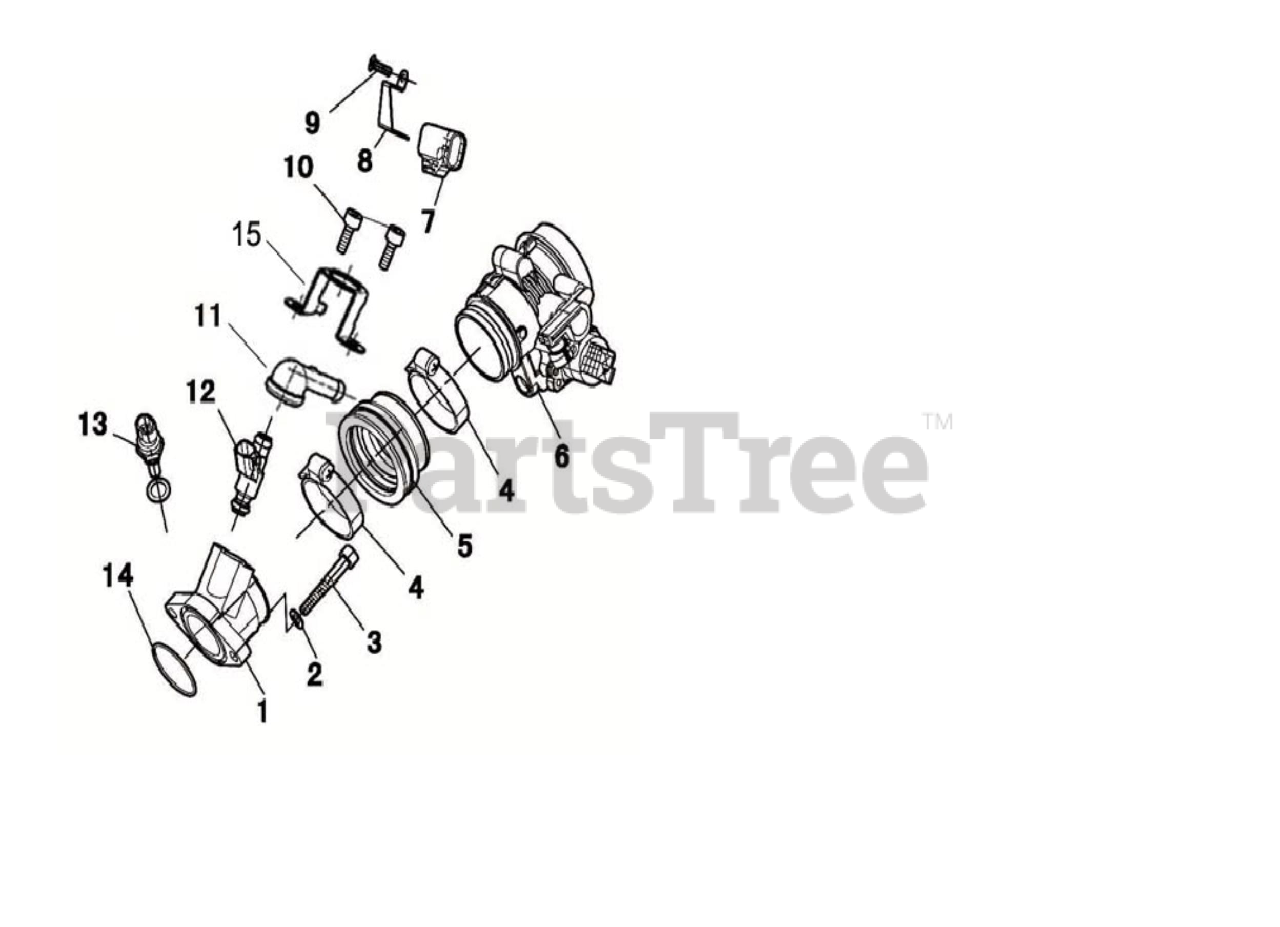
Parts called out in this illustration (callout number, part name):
1	ADAPTER ASSEMBLY
2	WASHER 8 X 16 X 1.5
3	HEXAGON SOCKET HEAD CAP SCREW M8 X 50
4	Hose Clamp Assy ?50??70
5	INLET PIPE JOINT
6	AIR THROTTLE ASSEMBLY
7	Temperature/Pressure Sensor
8	Press Plate,TMAP
9	Cross recessed pan head screw, single coil spring lock washer assemblies M4X8
10	HEXAGON SOCKET HEAD CAP SCREW M6 X 12
11	FUEL INJECTOR FIXED SEAT
12	FUEL INJECTOR?28160355?
13	Water Temperature Sensor
14	O-RING 44 X 2
15	FUEL INJECTOR CLAMP
